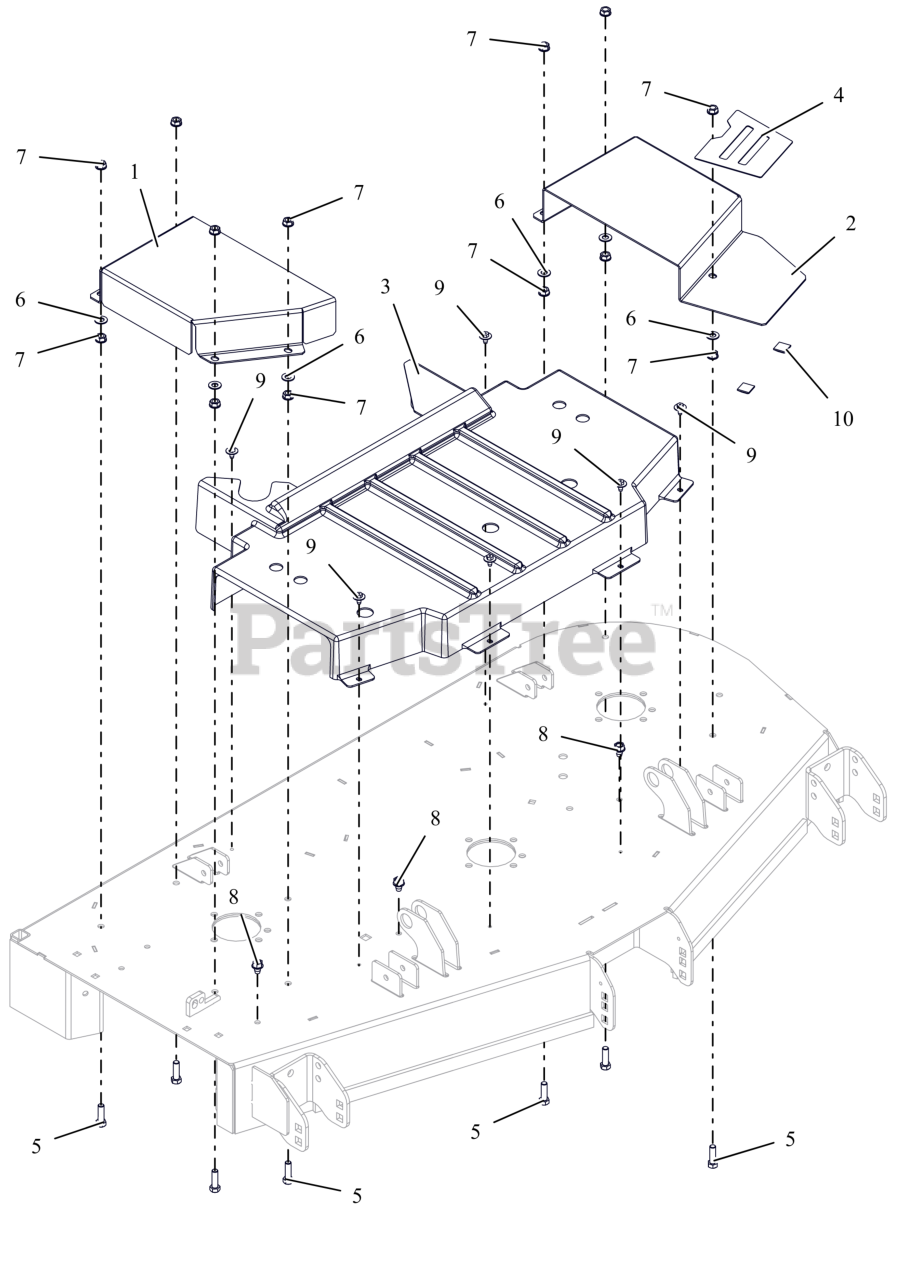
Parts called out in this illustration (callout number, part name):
1	GUARD, BELT 52" RIGHT CE (ORANGE)
2	GUARD, BELT 52" LEFT CE (ORANGE)
3	GUARD,CENTER,DECK SPINDLE CE
4	GRIP TAPE 52-60 BELT COVER
5	BLT, HEX .38-16X1.25 G5 ZCC
6	WSHR,FLT .406X.812X.065 ZCC
7	NUT, SPNLK-FLG .38-16 G5 ZCC
8	SCR,TAP .375-16X.50 HWH TR ZCC
9	SCR, TAP .25-20X.50 LG HWH ZCC
